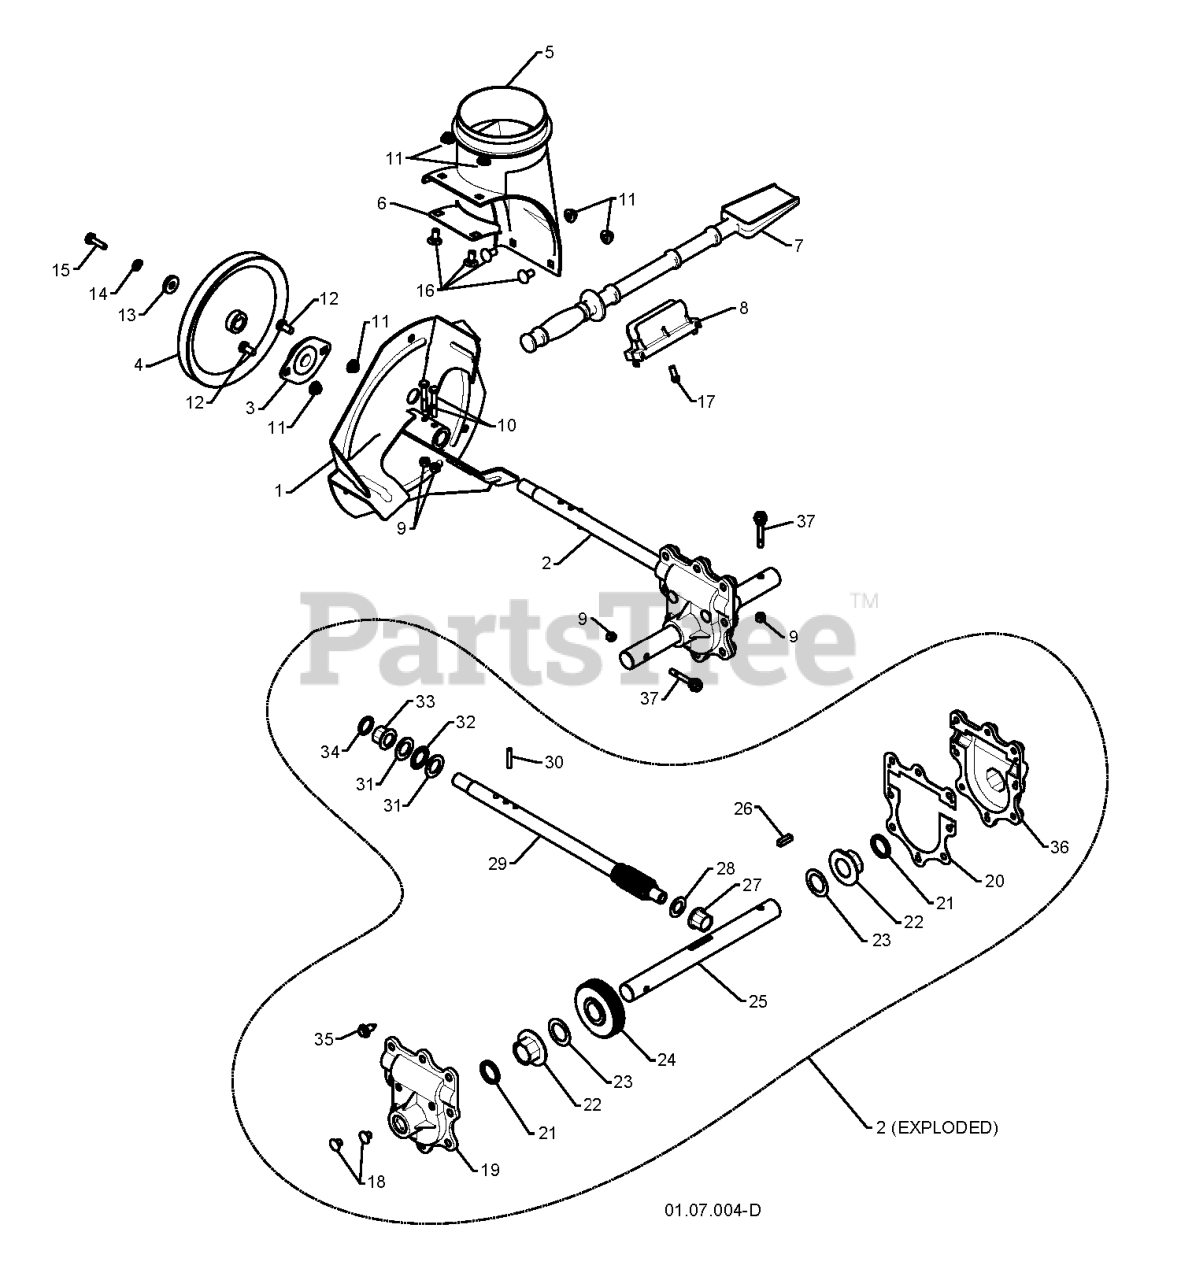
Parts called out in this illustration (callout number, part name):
1	IMPELLER ASSY
2	GEARBOX.ASSEMBLY.AUGER
3	BEARING FLANGE
4	PULLEY.IMPELLER.SNOW
5	BASE DISCHARGE CHUTE
6	BRACKET, CORNER DISCHARGE
7	CLEAN OUT TOOL
8	CLIP.CLEANOUT.TOOL
9	LOCKNUT.NYLOC.1/4-20
10	SCREW.HEX.HD1/4-20X
11	NUTNYLOK.FLRANGE.5/16-18
12	BOLT, HEX HEAD 5/16-18
13	WASHER, FLAT
14	WASHER.LOCK.HVY.HLCL.SPR.5/16
15	CAPSCREW.HX.HD.5/16-18X1.00.NY
16	BOLT.CARRIAGE.5/16-18X
17	SCREW.HWH.13-16-5.8.BZP
18	CASE PLUG
19	GEARBOX HOUSING-RH
20	GEARBOX GASKET
21	OIL SEAL
22	FLANGE BUSHING-1"
23	WASHER TRUST 1"
24	WORM GEAR
25	AUGER SHAFT
26	KEY, SQUARE 1/4 X .875
27	FLANGE BUSHING-5/8
28	WASHER, THRUST 5/8
29	SHAFT, IMPELLER
30	PIN, ROLL 3/16 X 1-1/8
31	WASHER, THRUST 3/4
32	BEARING TRUST 3/4 NTA-1220
33	BUSHING, FLANGE 3/4
35	HEX SCREW-5/16 X 3/4
36	HOUSING.GEARBOX.LH(SERVICE)
37	BOLT.SHOULDER.SHEAR.1/4-20.
